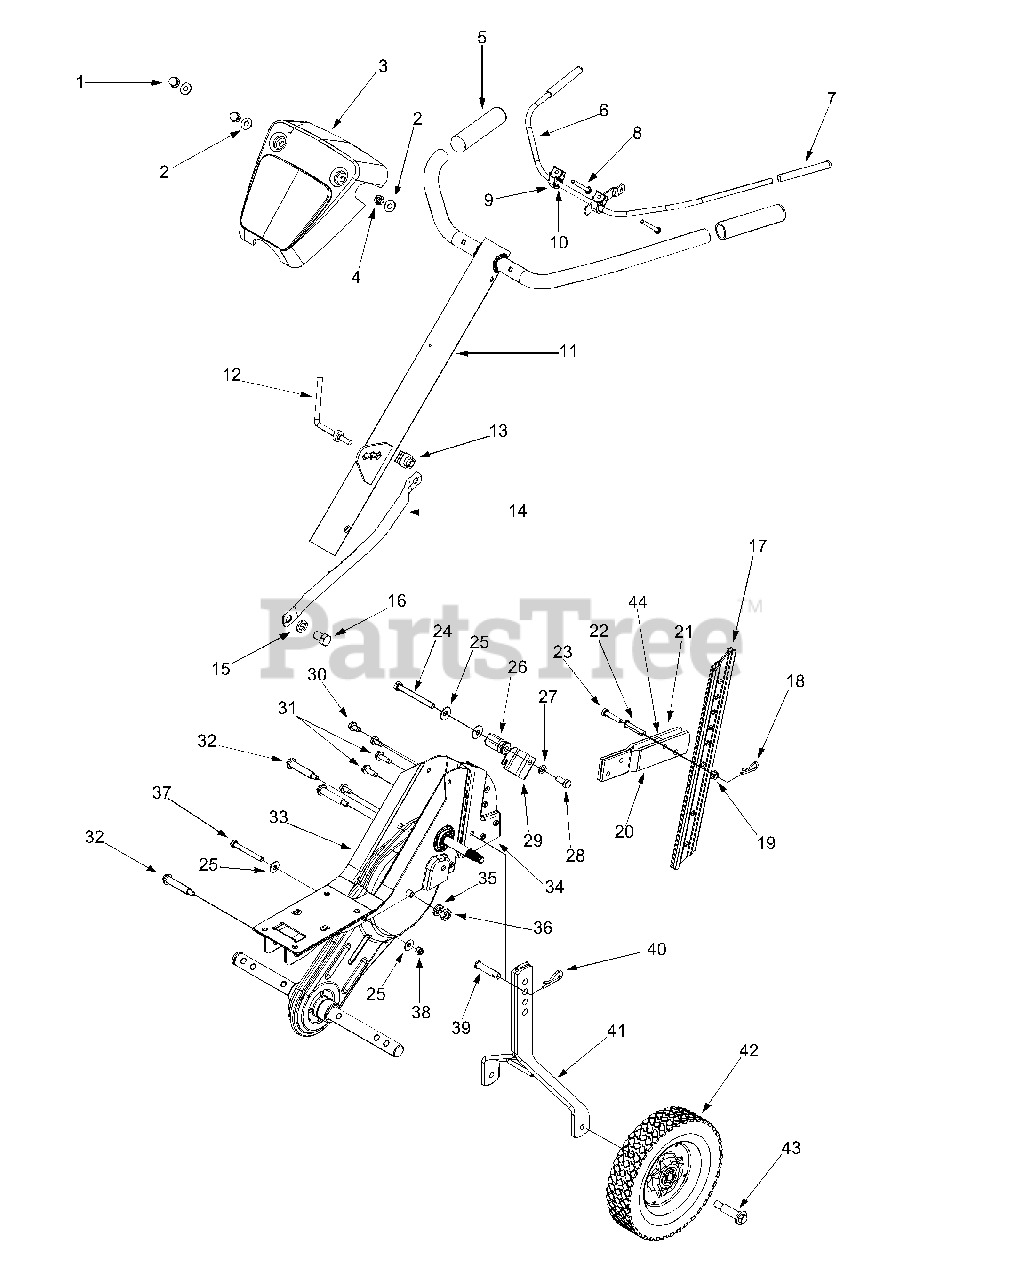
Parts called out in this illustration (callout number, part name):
1	Acorn Lock Nut 1/4-20
2	Flat Washer .271" I.D. x .630" O.D.
3	Handle Cover
4	Hex Nut 1/4-20 Gr.2
8	Hex Bolt 1/4-20 x 2.25"
9	Clutch Handle Holder
10	Flat Washer .385" I.D. x .62" O.D.
13	U Nut 5/16-18
16	Hex Bolt 1/2-20
19	Hex Flange L-Nut 5/16-18
23	Hex Bolt 5/16-18 x 1.5"
24	Hex Bolt 5/16-18 x 3"
25	Wash. Bell. .340" I.D. x .872" O.D.
26	Spec. Hex Nut
27	L-Wash. 5/16" I.D.
28	Hex Bolt 5/16-18 Gr. 5
30	Hex Wash Screw 5/16-18 x .62"
31	Hex Wash. Hd. TT-Tap Scr.
32	Shdl. Bolt 5/16-18
35	Lock Washer 7/16
36	Jam Nut 7/16-20 Gr. 2
37	Hex Bolt 5/16-18 x 2.75" Lg.
38	Hex Nut 5/16-18 Thd.
42	Wheel Ass'y 8" x 1.75"
43	Shoulder Screw .496 x 1.445
